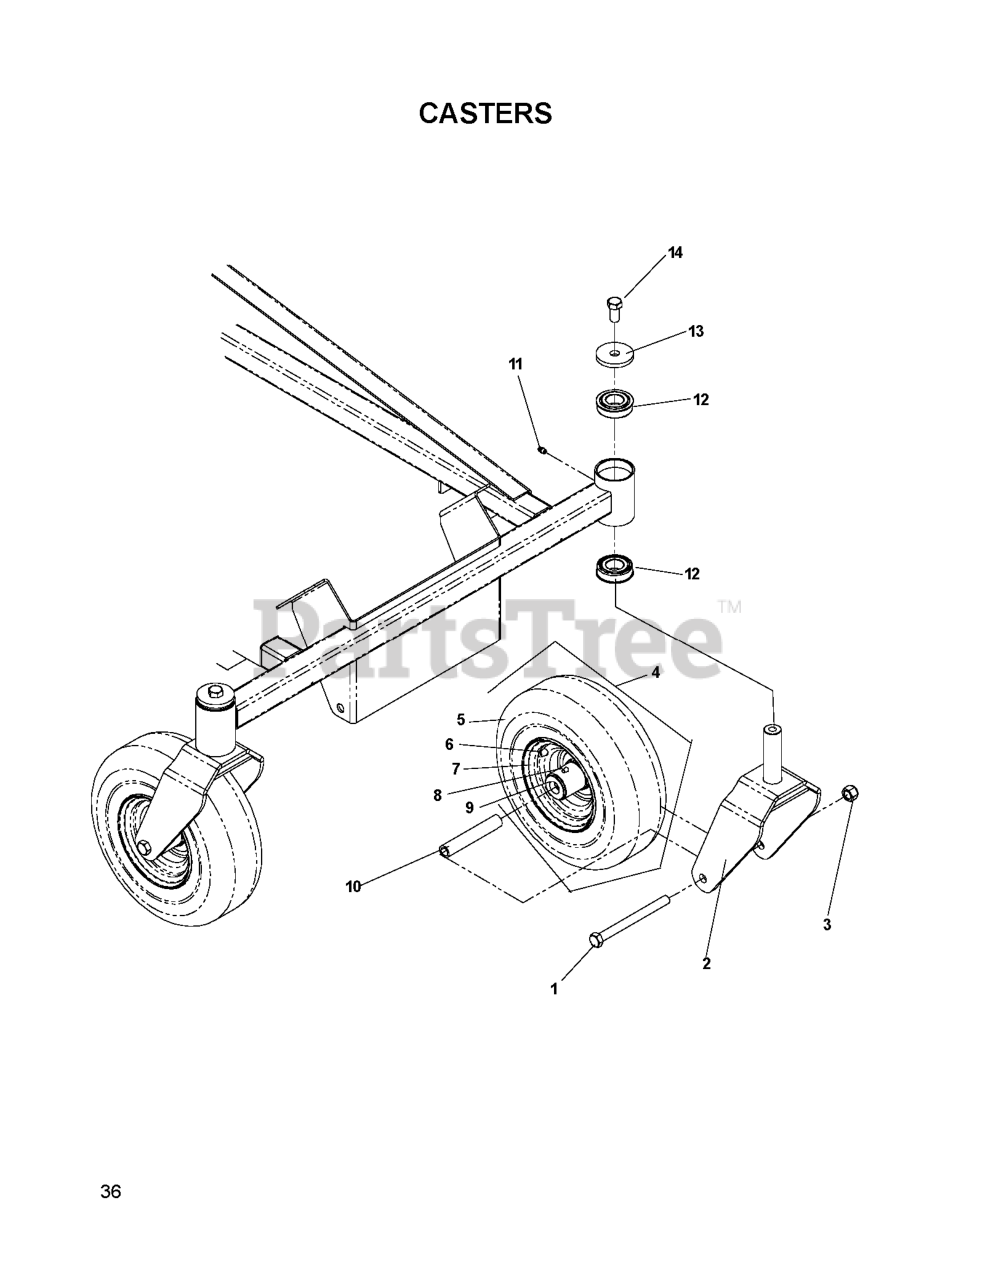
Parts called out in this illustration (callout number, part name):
1	HCS 1/2C X 5 1/2
2	CASTER YOKE - PAINTED
3	NUT 1/2-13 HEX NYLOC ZD
4	TIRE/WHEEL.CASTER
5	TIRE - CASTER
6	VALVE STEM TR-412
8	ZERK
9	BEARING RETAINER
12	BEARING FLANGED
13	HEAVY WASHER
14	HHCS 1/2-13 X 1
